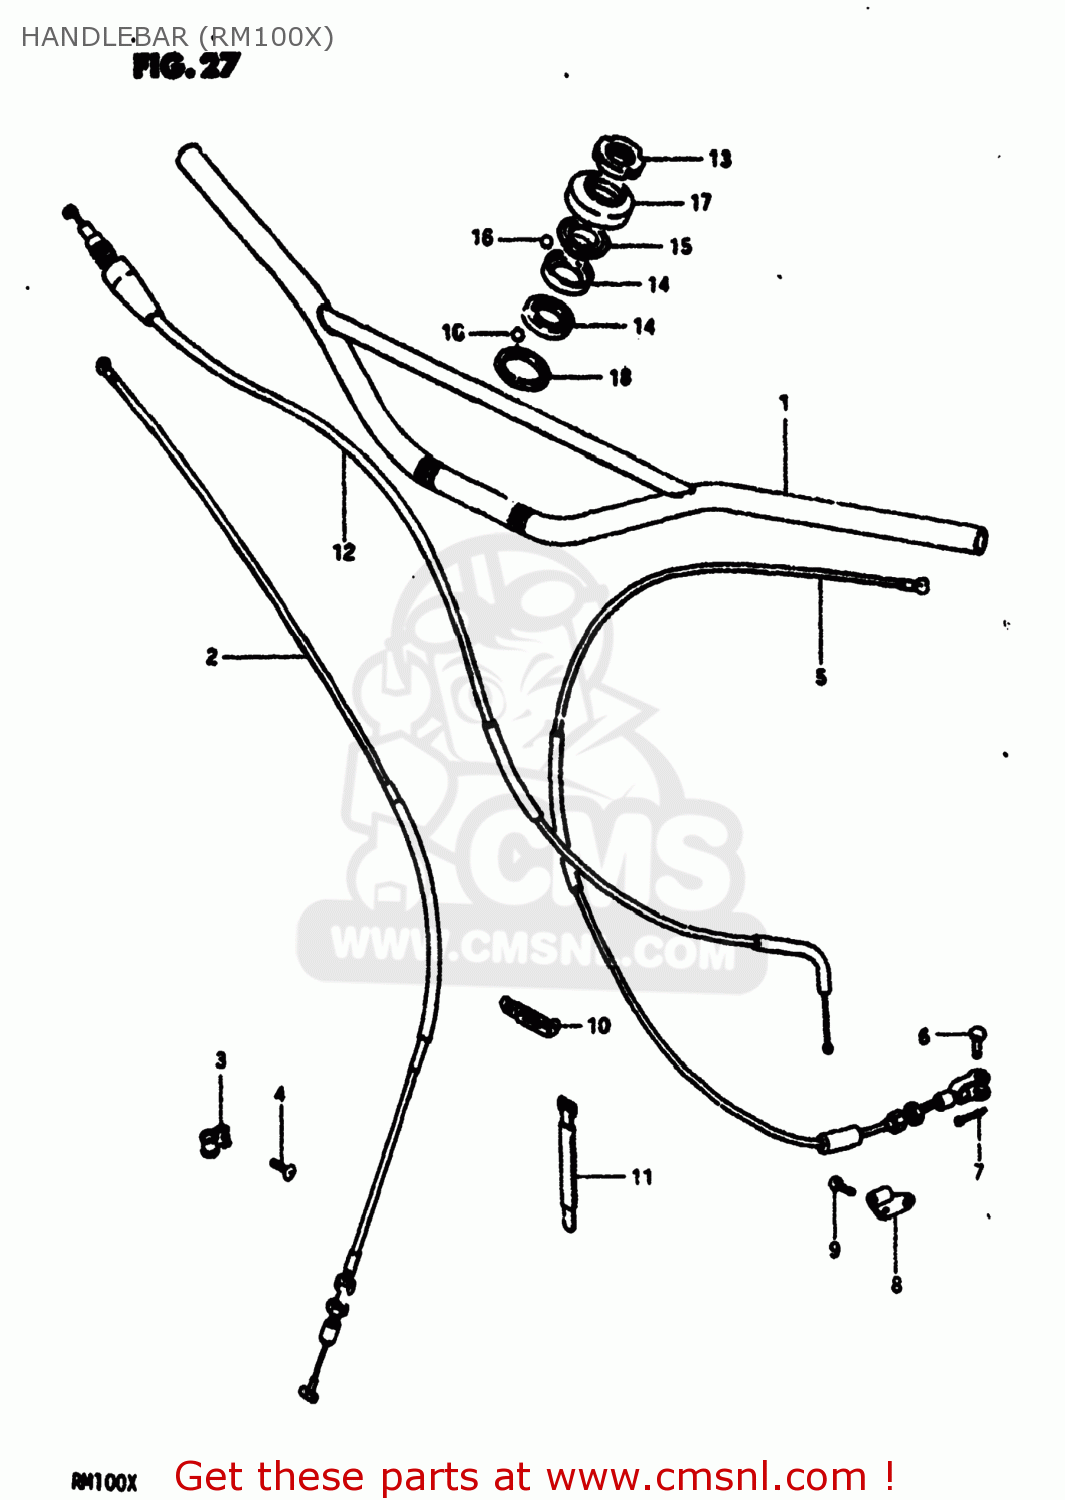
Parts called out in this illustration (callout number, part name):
1	HANDLEBAR
2	CABLE ASSEMBLY,FRONT BRAKE
3	CLIP,CABLE
4	SCREW
5	CABLE ASSY,CLUTCH
6	PIN(L:13)
7	PIN
8	STOPPER,CLUTCH CABLE
9	SCREW
10	CLAMP L:35
11	CLAMP
12	CABLE ASSEMBLY,THROTTLE
13	NUT,STEERING STEM
14	RACE,STEERING,INNER,UPPER
15	RACE,STEERING,OUTER,UPPER
16	BALL
17	SEAL,STEERING UPR DUST
18	DUST SEAL,STEERING HEAD
